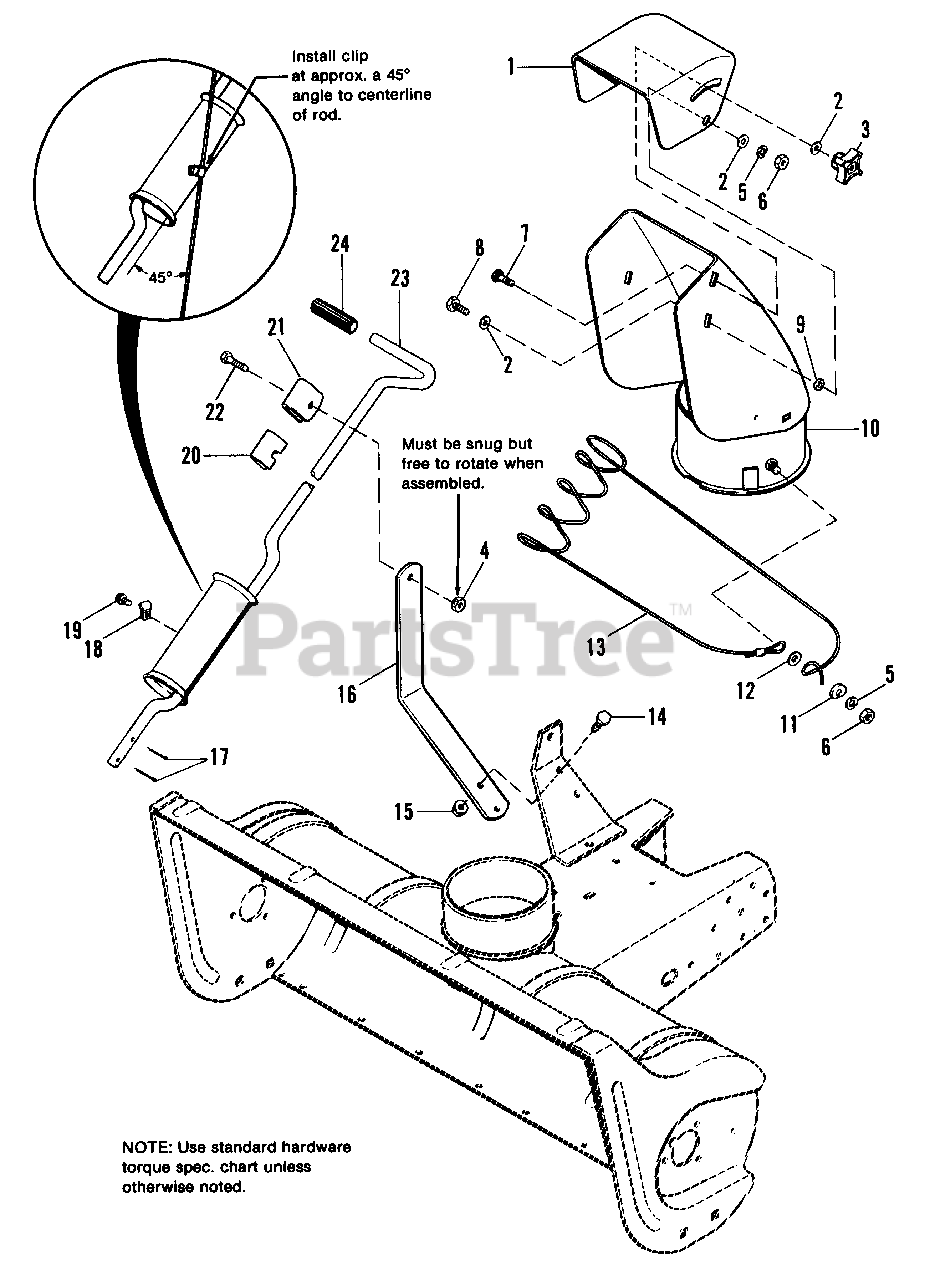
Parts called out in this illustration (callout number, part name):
1	DEFLECTOR
2	WASHER, Plain, 5/16
4	LOCKNUT, Hex, 5/16-18
5	LOCKWASHER, 5/16
6	NUT, Hex, Full, 5/16-18
7	BOLT, Carriage, 5/16-18 x 1
8	CAPSCREW, Hex, 5/16-18 x 3/4
10	CHUTE ASSY.
11	WASHER, Cup
12	WASHER, Plain, 1/4
13	CABLE ASSY.
14	CAPSCREW, Hex, 3/8-16 x 1
15	NUT, Hex, Flange, 3/8-16
16	ARM, Support
17	PIN, Cotter, 3/32 x 3/4
19	SCREW, Hex, Taptite, 1/4-20 x 3/8
22	CAPSCREW, Hex, 5/16-18 x 1-1/2
23	ROD ASSY., Spout
24	GRIP, Handle
